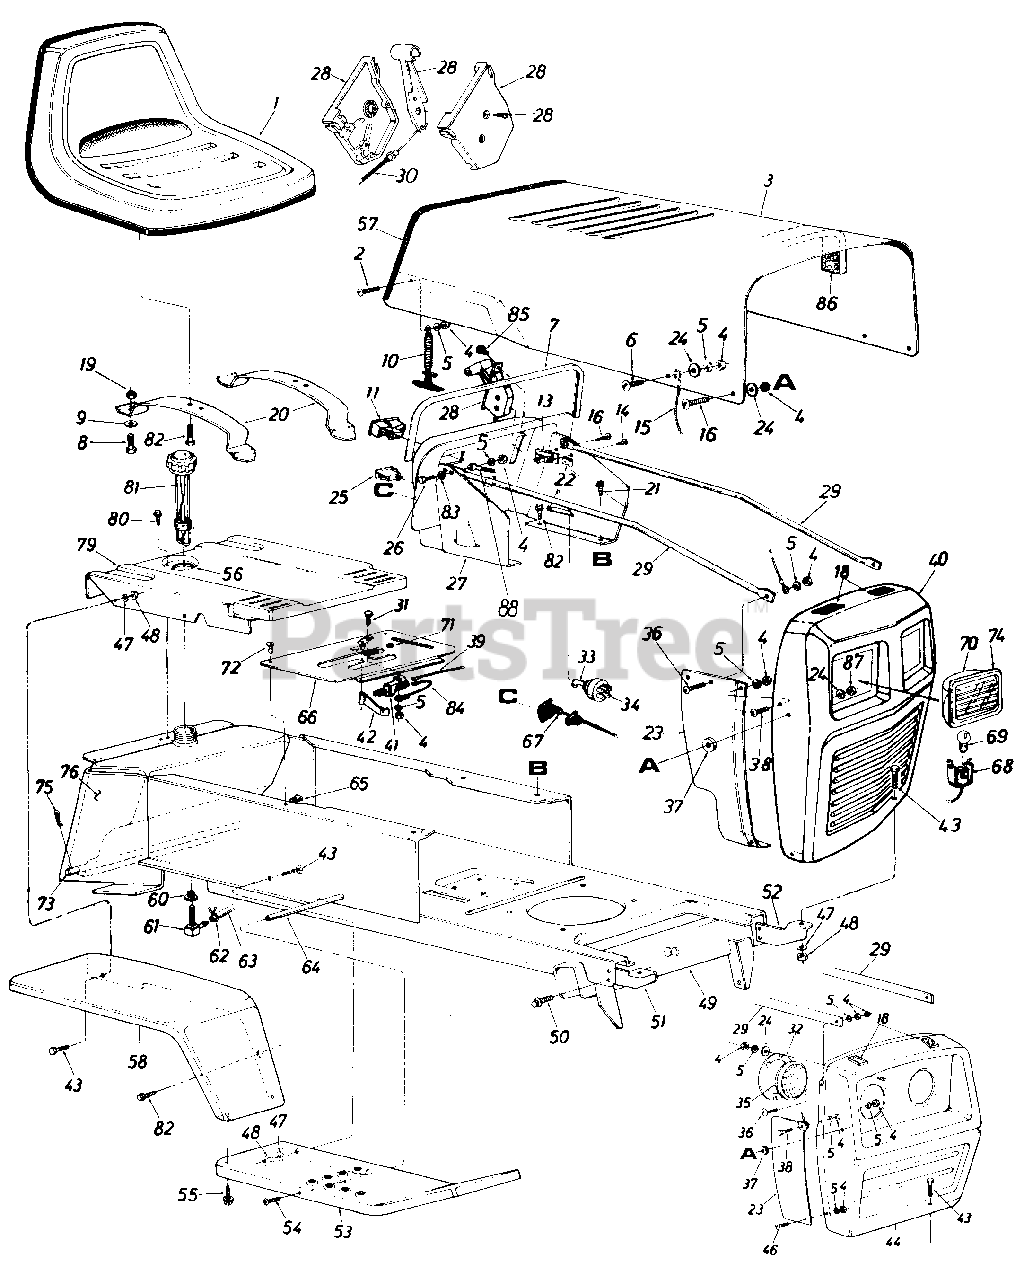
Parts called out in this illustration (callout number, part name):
1	Seat Assembly
2	Truss Mach. Scr. 1/4-20 x .50" Lg.*
5	L-Wash. 1/4" I.D.*
6	Truss Mach. Scr. 1/4-20 x .50" Lg.*
7	Vinyl Molding Strip-29"
8	Hex Nylon Scr. 1/2-13 x .75" Lg.
9	Fl-Wash. .50" I.D. x 1.00" O.D. x .090
10	Hood Latch Ass'y.
11	Ammeter
13	Circuit Breaker 8 Amp.
14	Hex Tap Scr. #10 x .50"
15	Hood Stop
16	Truss Mach. Scr. 1/4-20 x .75" Lg.*
18	PVC Foam Strip 1/2 x 1.00" x 2.00" Lg.
19	Hex Nut 1/2-13 Thd.*
22	Speed Nut #10Z
23	Grille Side Panel-R.H.
24	Fl-Wash. 1/4" I.D.
25	Light Switch
26	Truss Hd. Scr. 1/4-20 x 1.00" Lg.*
27	Dash Panel Ass'y.
28	Throttle Control Box Comp.
29	Grille Positioning Rod
30	Throttle Control Cable
31	Hex Bolt 1/4-20 x .50" Lg.*
32	Head Lamp Retainer
33	Ignition Key
34	Ignition Switch
35	Head Lamp
36	Truss Machine Scr. 1/4-20 x .75" Lg.*
37	Rubber Washer
38	Truss Mach. Scr. 1/4-20 x .50" Lg.*
39	Reverse Lockout Wire Harness
42	Switch Actuator Spring Lever
43	Hex Bolt 5/16-18 x .75" Lg.
44	Grille (Painted)
46	Truss Mach. Scr. 1/4-20 x .50" Lg.
47	L-Wash. 5/16" I.D.
48	Hex Nut 5/16-18 Thd.
49	Lower Frame Ass'y.
50	Hex Thd. Rolling Scr. 5/16" x.75" Lg.
51	Grille Mount Brkt.-R.H.
52	Grille Mount Brkt.-L.H.
53	Running Board-R.H.
54	Truss Mach. Scr. 5/16-18 x .75" Lg.
55	Hex Thd. Rolling Scr. 5/16-24 x .75" Lg.
56	Grommet
57	Vinyl Moulding Strip-30"
58	Fender Ass'y.-R.H.
60	Bushing
61	90ø Nipple
62	Hose Clamp 3/8"
63	Gas Line 46" Lg.
64	Running Board Rod
65	Speed Nut #10-24
66	Transmission Cover Ass'y.
67	Choke Control Comp.
68	Socket
69	Lamp
70	Headlight Housing
71	Snap Bushing
72	Truss Hd. Scr. #10 x .50"
73	Hitch Rod
74	Lens
75	Internal Cotter Pin
76	Gas Tank
79	Seat Plate
80	Hex Thd. Rolling Scr. 5/16-24 x .75" Lg.
81	Gas Gauge
82	Hex Thd. Rolling Scr. 5/16-24 x .75" Lg.
83	External Wash. 1/4" I.D.
84	Electric Wire
85	Truss Mach. AB-Tap Scr. #10 x .50" Lg.
86	PVC Foam Strip
87	Hex L-Nut 1/4-20 Thd.
88	Ground Wire
